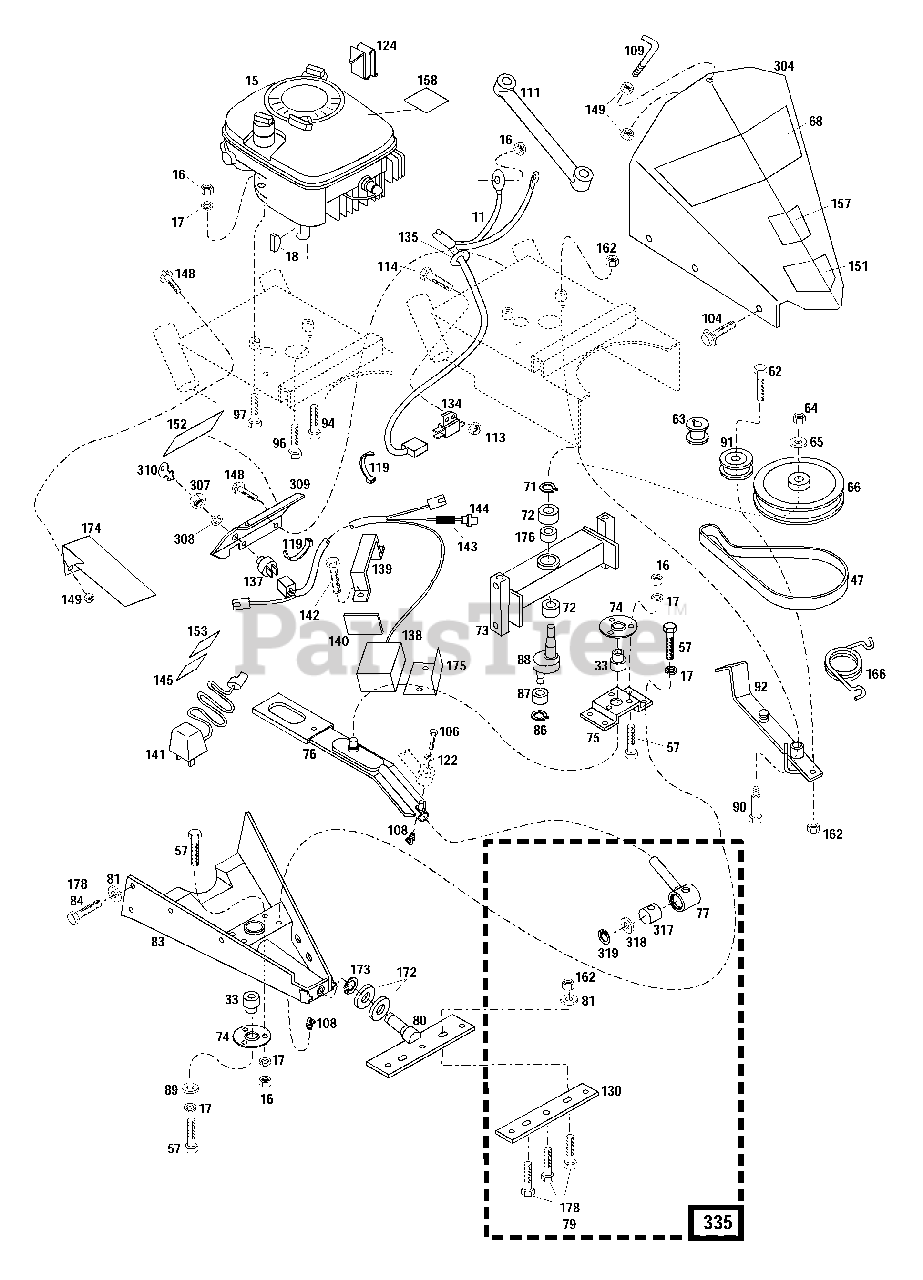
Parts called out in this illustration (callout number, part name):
11	Operator Interlock Harness
15	Engine, Briggs & Stratton, 3.5 HP
16	Hex Nut, 5/16-18
17	Lockwasher, 5/16
18	Woodruff Key, #6, 5/23 x 5/8
33	Bearing Insert
57	Hex Head Capscrew, 5/16-18 x 3/4
62	Hex Head Capscrew, 3/8-16 x -1/2
63	Engine Pulley
64	Hex Nut, 5/8-18
65	Flat Washer, 5/8
66	Eccentric Pulley
68	Decal, Troy-Bilt
71	Retaining Ring
72	Ball Bearing
73	Housing Assembly
74	Bearing Retainer
75	Upper Pivot Bearing Support
76	Eccentric Arm Assembly
77	Pitman Assembly
79	Hex Hd. Capscrew, 3/8-16 x 1-1/4, Grade 8
80	Attachment Mounting Bracket Assembly
81	Flat Washer (hardened), 5/16
83	Front Housing Assembly
84	Hex Head Capscrew, 3/8-16 x 3/4, Grade 8
86	Retaining Ring
87	Eccentric Bearing
88	Eccentric Shaft
89	Flat Washer, 5/16
90	Shoulder Screw
91	Idler Pulley, 3 x 1
92	Knife Clutch Arm
94	Hex Head Capscrew, 5/16-18 x 3
96	Hex Head Capscrew, 5/16-18 x 4, Grade 5
97	Hex Head Capscrew, 5/16-18 x 3-1/2
104	Self-Tapping Screw, 5/16-18 x 5/8
106	Hex Head Capscrew, 1/4-20 x 1-1/4
108	Grease Fitting, 1/4-28 x 90°.
109	Upper Hook, 1/4-20
111	Bungi Strap, 14-1/2"
113	Hex Nut, #10-24
114	Truss Hd. Screw, #10-24 x 5/8
119	Cable Tie
122	Flat Washer, 1/4
124	Engine Cable Clip
130	Doubler Bracket
134	Switch
135	Grommet
137	Key Switch
138	Battery
139	Battery Clamp
140	Battery Pad
141	Charger
142	Thread Forming Screw, 1/4-20 x 3/8
143	2-amp Fuse
144	Start Harness
145	Decal, Electric Start
148	Self-Tapping Fl. Screw, 1/4-20 x 1/2
149	Flange Lock Nut, 1/4-20
151	Decal, OPEI Danger
152	Decal, Warning
153	Decal, American Legend
157	Decal, Danger
158	Decal, Hot Surface
162	Center Lock Nut, 3/8
166	Torsion Spring
172	Flat Washer
173	Retaining Ring
174	Switch Cover
175	Heat Reflector
178	Loctite (R) Thread Compound
304	Fender
307	Nut
308	Lock Washer
309	Keyswitch Plate
310	Key
317	Pitman Bearing
318	Thrust Washer
319	Retaining Ring
335	See "Blades"
